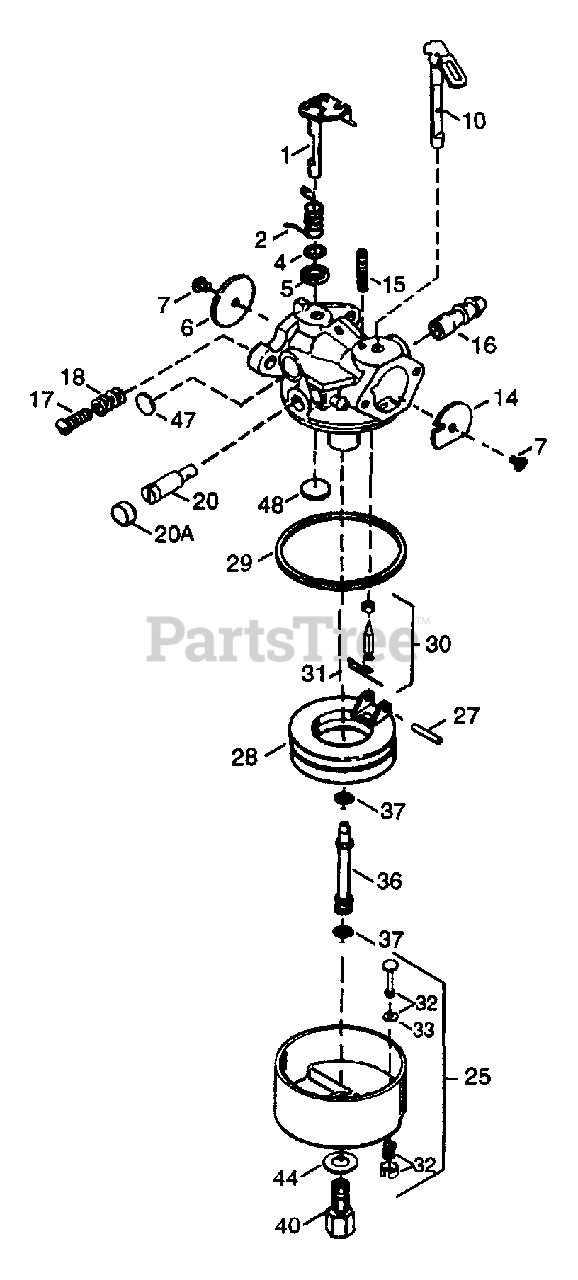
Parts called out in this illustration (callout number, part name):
1	Throttle Shaft & Lever Assembly
2	Throttle Return Spring
4	Dust Seal Washer
5	Dust Seal
6	Throttle Shutter
7	Shutter Screw
10	Choke Shaft & Lever Assembly
14	Choke Sutter
15	Choke Positioning Spring
16	Fuel Fitting
17	Throttle Crack Screw/Idle Speed Screw
18	Tension Spring
20	Idle Restrictor Screw
20A	Idle Restrictor Screw Cap
25	Float Bowl Assy
27	Float Shaft
28	Float
29	Float Bowl "O" Ring
30	Inlet Needle, Seat & Clip
31	Spring Clip
32	Bowl Drain Assembly
33	Drain Plunger Gasket
36	Main Nozzle Tube
37	"O" Ring, Main Nozzle Tube
40	High Speed Bowl Nut
44	Bowl Nut Washer
47	Welch Plug, Idle Mixture Well
48	Welch Plug, Atmospheric Vent
